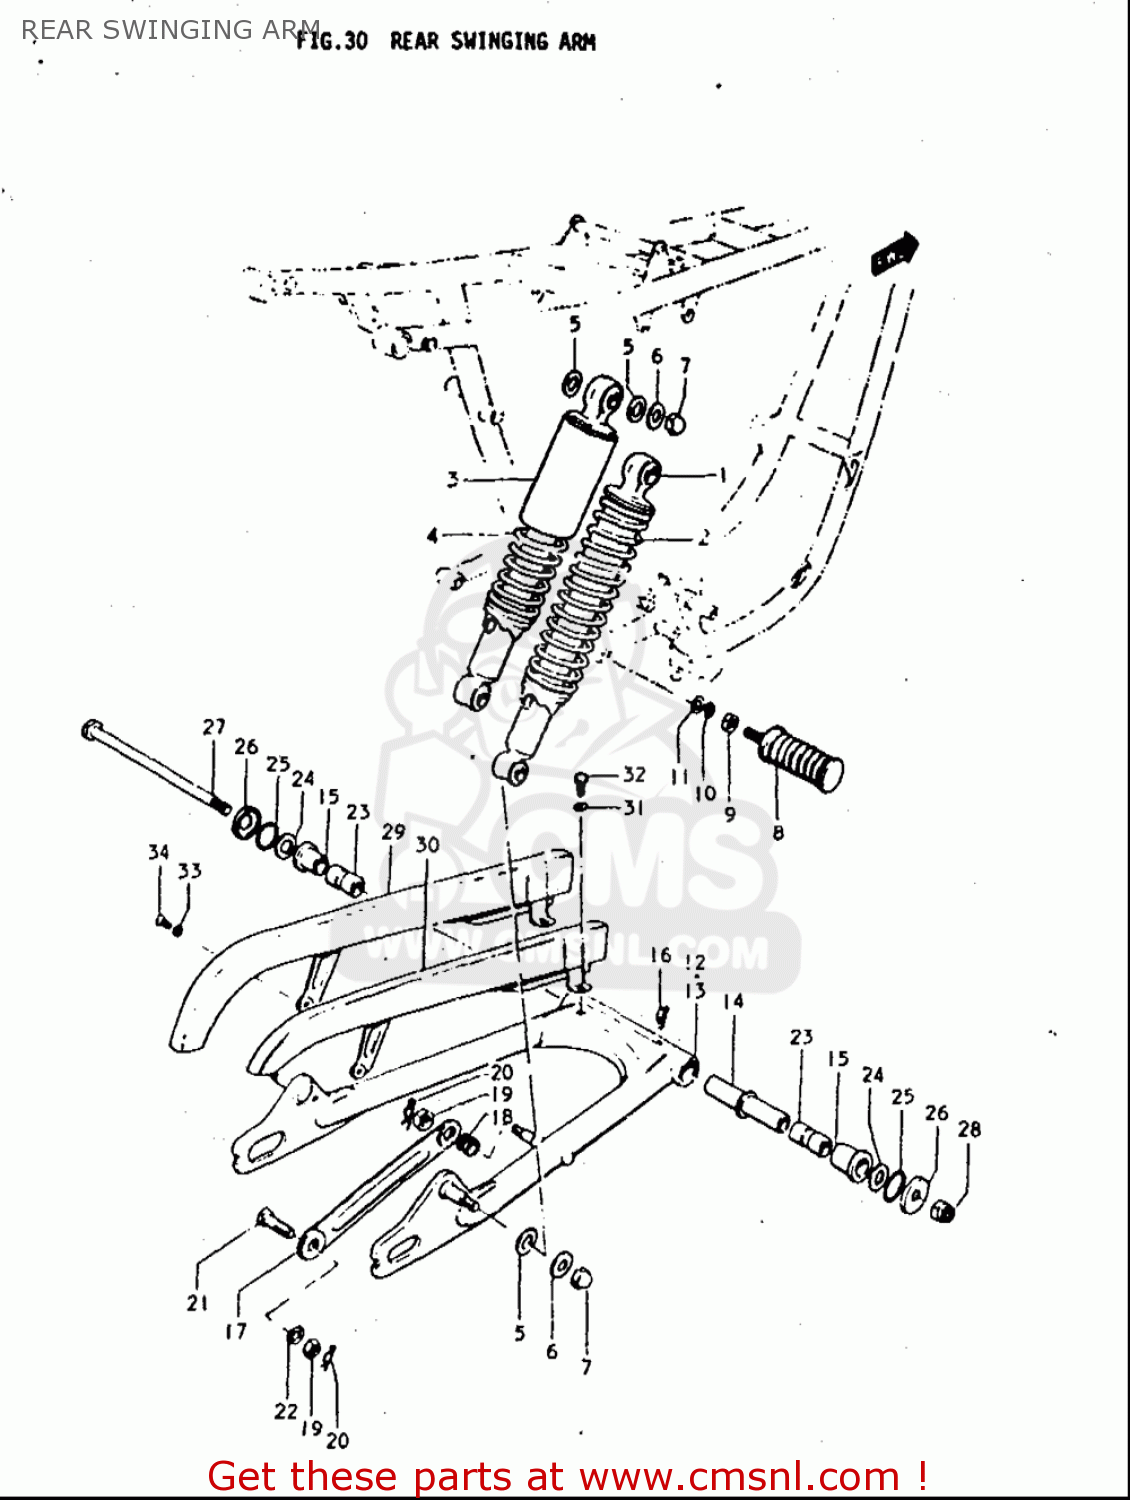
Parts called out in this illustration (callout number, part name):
5	WASHER (10.5X24X2.3)
6	WASHER
7	NUT
8	FOOTREST SET,PILLION
9	NUT
10	WASHER,LOCK
11	WASHER
15	BUSH
16	NIPPLE,GREASE
18	SPRING
19	NUT
20	CLIP
21	BOLT(10X31)
22	WASHER,LOCK
23	SPACER
24	WASHER(14.5X29X2.3)
25	O RING(D:3,ID:29.5)
26	COVER
31	WASHER,LOCK
33	TOOTHED WASHER
